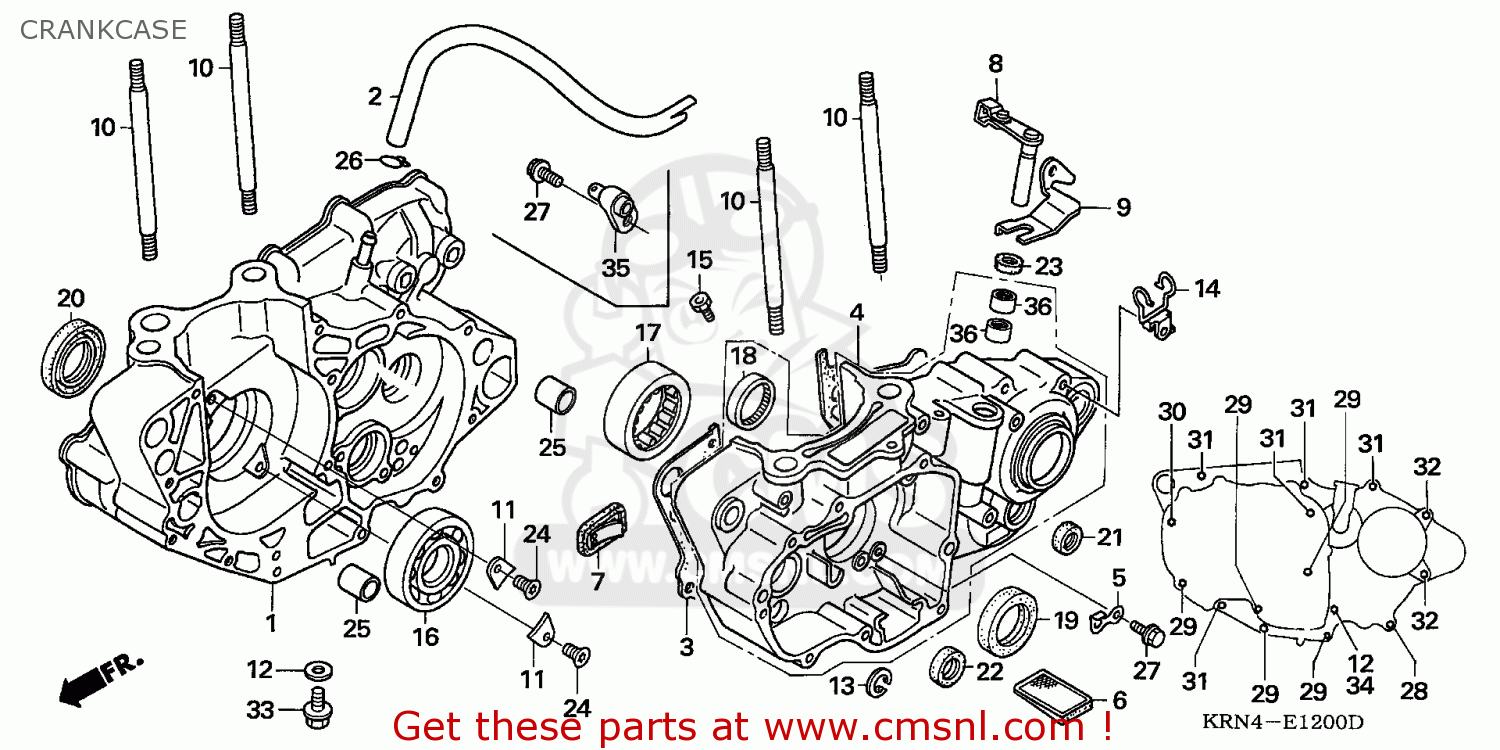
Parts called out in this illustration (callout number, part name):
1	CRANKCASE COMP,RI
2	TUBE,BREATHER
3	GASKET,CRANKCASE (NAS)
4	CRANKCASE COMP,LE
5	PLATE,CAM CHAIN G
6	SCREEN,OIL FILTER
7	REED VALVE COMP
8	LEVER COMP,CLUTCH
10	BOLT,STUD 10X135
11	PLATE,BRG HOLD
12	WASHER,8MM
13	CIRCLIP,SPL 33MM
14	GUIDE COMP,TUBE
16	BRG,BALL RADIAL 3
17	BRG,ROLLER SPL
18	NEEDLE BRG
19	OIL SEAL,35X52X7
20	OIL SEAL,39X56X7
21	OIL SEAL,14X22X5
22	OIL SEAL,20X33X5
23	OIL SEAL,12X18X3
24	SCREW,FLAT SPL 6X
25	DOWEL,PIN,14X20
27	BOLT,FLANGE,6X12
28	BOLT,FLANGE,SH,6X40
29	BOLT,FLANGE,6X45
30	BOLT,FLANGE,6X60
31	BOLT,FLANGE,6X70
32	BOLT,FLANGE,6X75
33	BOLT,FLG DR 8X25
34	BOLT,FLANGE DR 8X
35	JET COMP,PISTON #
36	NEEDLE BRG
